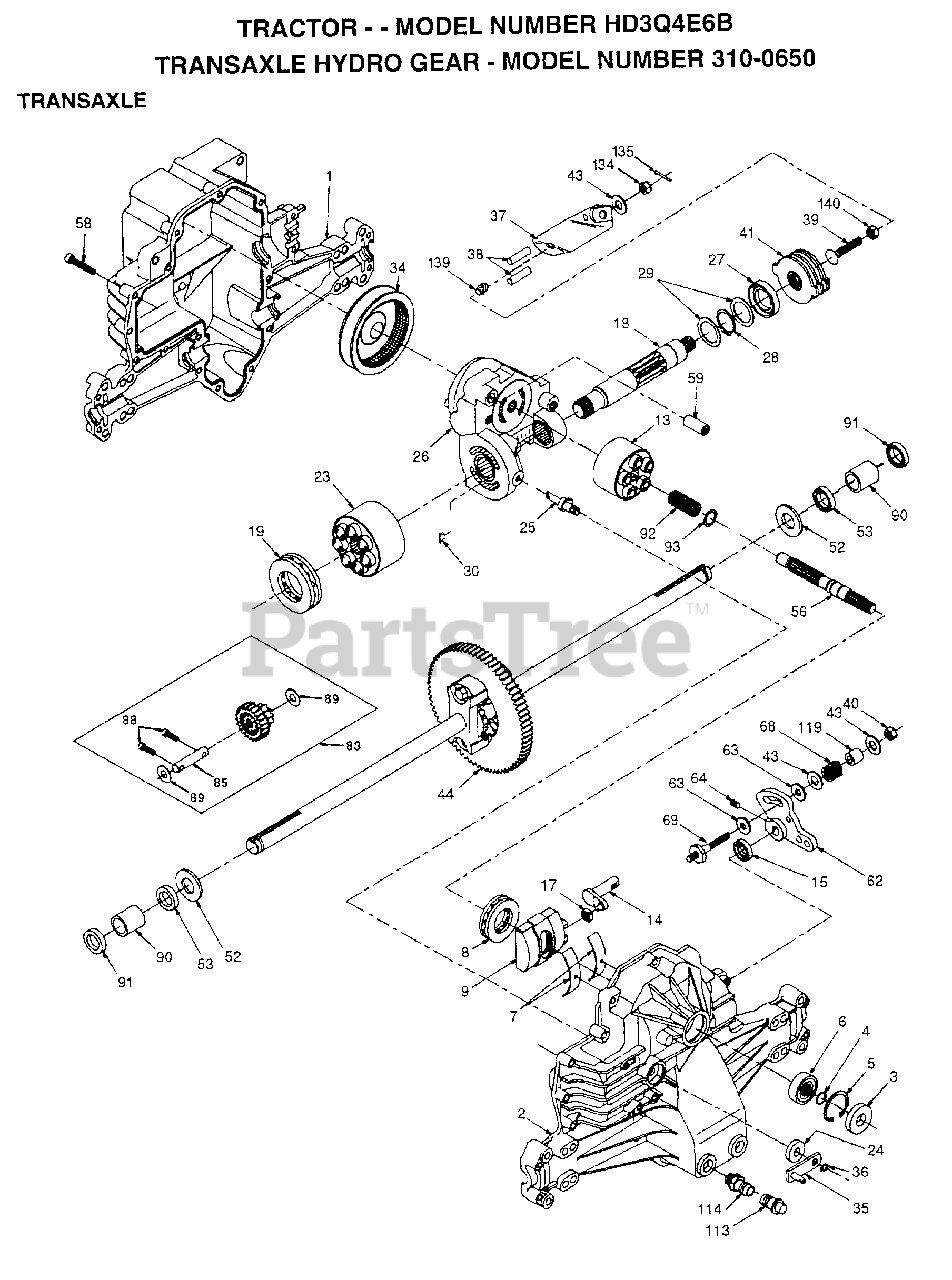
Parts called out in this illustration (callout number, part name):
1	HOUSING.L.50074RM
2	HOUSING.UP.70125
3	SEAL.9008000-0128
4	RING.RET.2003016.
5	RING.RET.2003052.
6	BEARING.(50552)42X68X16
7	CRADLE- 2003023.
8	BEARING.THU.50551
9	SWASHPLT.2003087.
13	BLOCK.CLYN.70079.
14	ARM.TRUN.2003005.
15	SEAL.9008000-0126
17	GUIDE.2000015.
18	SHAFT.MOTOR.50449
19	BEARING.THU.50552
23	BLOCK.CYLIN.70082
24	SEAL.LIP.45074
25	ACTUATOR.2003555
26	KIT.CEN.SEC.70250
27	SEAL.LIP.45075
28	RING RETAIN 50007
29	WASHER.44872
34	ELEMENT.OIL.44964
35	ARM.BYPASS.50270
36	RING.RETAIN.44870
37	ARM.ACTUAT.23710
38	PIN.ACTUAT.44891
39	BOLT.50316
40	NUT.LOCK.HX.50317
41	KIT.BRAKE.70135
43	WASHER HYD 44130
44	DIFFRENTIAL.70226
52	WASHER.HYD.44875
53	SEAL.HYDRO.45076
56	SHAFT.INPUT.50005
58	BOLT.1/4-20.44876
59	PIN.HYDRO.50002
62	ARM.CONTROL.50254
63	PUCK.DAMPER.50281
64	SCREW.SET.50018.
68	SPRING.HYD.50277
69	STUD.5/16-24.DANA
83	JACKSHAFT/PINION GEAR.70132
85	PIN.SHAFT 50559
88	SCREW.CAP.50154.
89	WASHER.HYD.50132
90	BEARING.SLV.50118
91	SEAL.WIPER.50941
92	SPRING.2003014.
93	WASHER.2003017
113	CAP.VENT.70109
114	O-RING.ASM.70110
119	SPACER.HYD.50278
134	NUT.CAS.HYD.44142
135	PIN.COT.HYD.44101
139	SPRING.COMP.50431
140	NUT.HEX.50269
